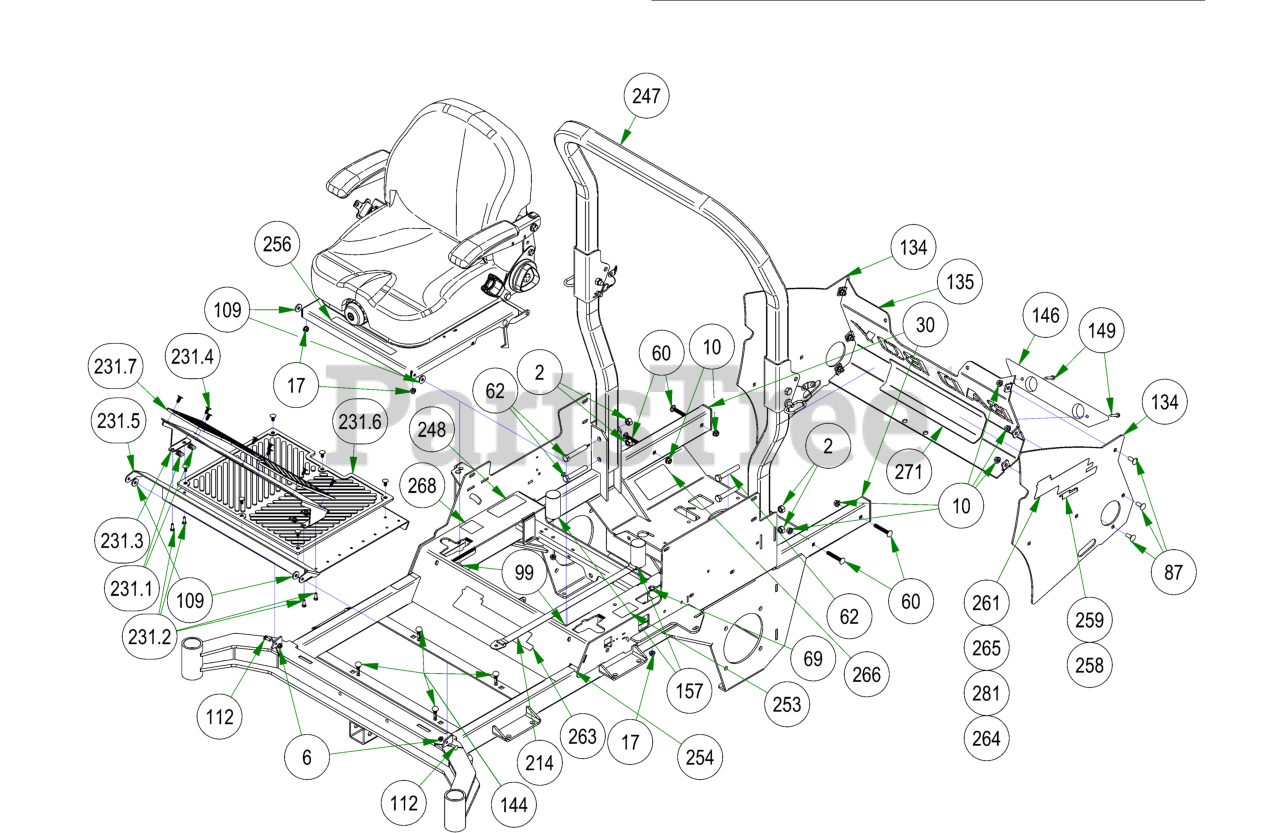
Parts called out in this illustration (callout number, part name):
2	1/2-13 HEX 2-WAY REVERSIBLE CENTER LOCKNUT Grade B ZINC
6	1/4-20 NYL INSERT FLANGE LOCKNUT ZINC
10	3/8-16 NYLON INSERT FLANGE LOCKNUT (GR.F) ZINC
17	5/16-18 NYLON INSERT FLANGE LOCKNUT ZINC
20	5/16-18 HEX SERRATED FLANGE NUT HARD/ZINC
30	1 1/2 x 3 Frame Plug
56	M6-1.0 X 16MM DIN 933 HEX TAP BOLT (CL 8.8) ZINC
60	3/8" x 2 1/2" Carriage Bolt
62	1/2-13 X 3-1/4 HEX CAP SCREW (GR.5) ZINC
69	5/16-18 X 1 HEX CAP SCREW (GR.5) ZINC
87	3/8-16 X 1 CARRIAGE BOLT (GR.5) ZINC
99	5/16-18 X 1 CARRIAGE BOLT (GR.8) ZINC
109	.360 ID X .983 OD X .120 THICK FLAT WASHER NYLON
112	1/4-20 X 3/4 CARRIAGE BOLT (GR.5) ZINC
133	R-SERIES SEAT PLATE ASSEMBLY
134	Rebel Rear Cover Side Plate
135	2019 Vertical Rear Cover Tailgate - Black
144	2023 Floor Board Rubber Bumper
146	2017 XP Bumper
149	1/4-14 X 1-1/2 HEX WASHER UNSLOT TEK/3 ZINC
157	2019 Bad Boy X Cylindrical Seat Mount
214	Seat Strap with Buckles
215	2019 Outlaw EPA Cannister Assembly
224	2023 Rebel Frame - Painted
225	2021 Rebel Seat
231	R-Series Floorboard Assembly
231.1	1/4-20 Cage Nut
231.2	1/4-20 X 3/4 HEX CAP SCREW (GR.5) ZINC
231.3	OUTLAW ADJUSTABLE FOOT PLATE-ORANGE
231.4	Ratchet Fastener
231.5	2019 Outlaw Floorboard
231.6	MAT (FLOOR)
231.7	MAT (FOOT PLATE)
247	2019 2X2 Folding ROPS
248	2023 EPA Build Date Punch Decal
253	2018 Out/XP/Diesel Brake Decal
254	2018 LH/RH Steering Control Decal Roll
256	Outlaw Warning Decal
258	2022 Powered By Kawasaki Decal
259	2022 Powered By Kohler Decal
261	2019 Rebel 852cc Backplate Cluster
263	2019 Rebel Cooler Cover Decal
264	2019 Rebel 747cc Backplate Cluster
265	2019 Rebel 999cc Backplate Cluster
266	2019 Rebel Pump Belt Route Decal
268	2019 Deck Release Decal
269	Control Adj. Control Rod Decal
270	Control Adj. Control Dampener Decal
271	Heat Shield (Fiberglass Adhesive)
281	Rebel Kawasaki 822cc Backplate Decal
